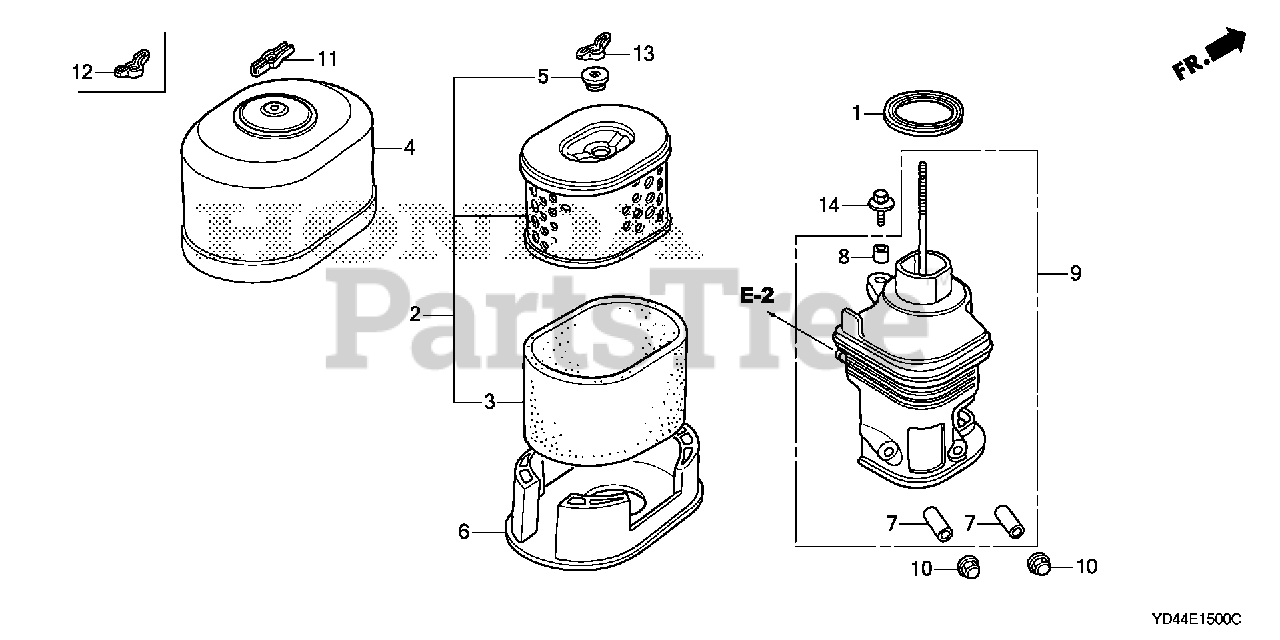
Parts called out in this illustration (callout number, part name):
1	GASKET, ELBOW
2	ELEMENT, AIR CLEANER
3	FILTER (OUTER)
4	COVER, AIR CLEANER (STD)
5	GROMMET, AIR CLEANER
6	NOSE, MUFFLER
7	COLLAR, AIR CLEANER
8	COLLAR B, AIR CLEANER
9	ELBOW, AIR CLEANER
10	NUT, FLANGE (6MM)
12	WINGNUT, TOOL BOX SETTING
13	WINGNUT, TOOL BOX SETTING
14	BOLT-WASHER (6X22)
